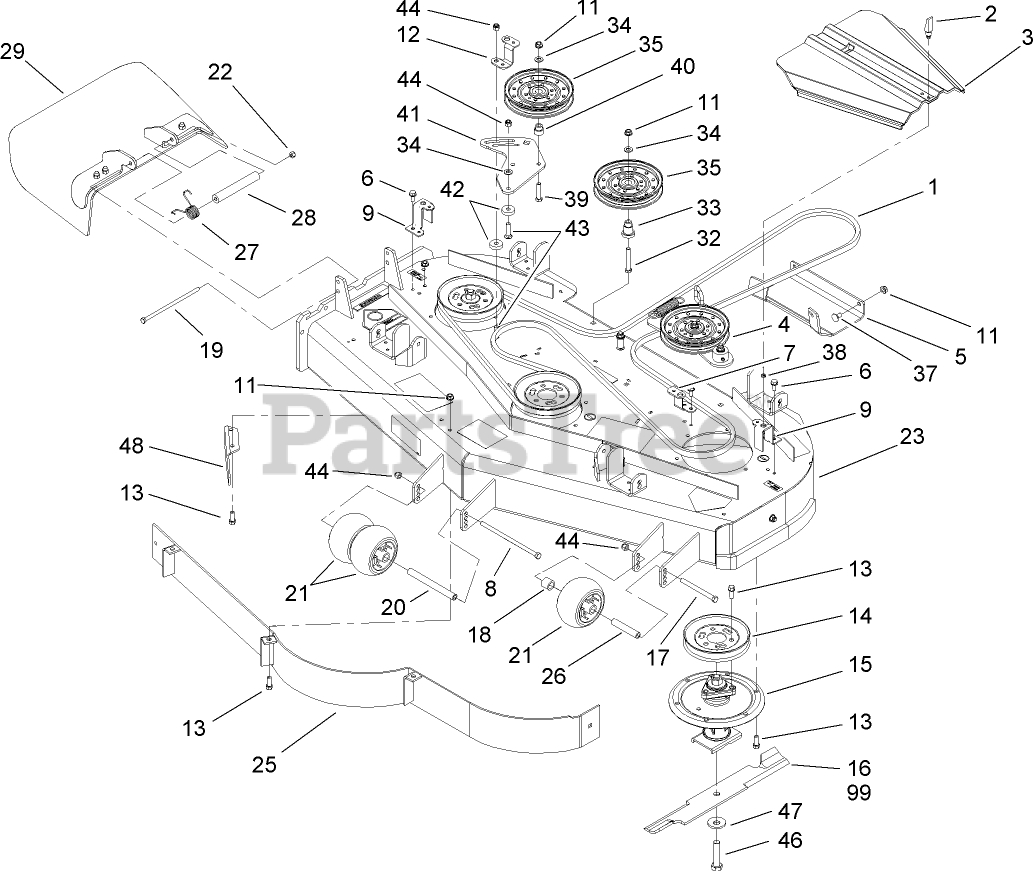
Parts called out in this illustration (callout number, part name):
1	BELT-V
2	LATCH-SWELL
3	COVER-BELT
4	SPRING IDLER ASM
5	Plate-Skid
6	SCREW-HWHTF
7	BRACKET-COVER, TALL
8	SCREW-HH
9	BRACKET-COVER
11	NUT-HHF, WHIZ
12	BRACKET-COVER, SHORT
13	SCREW-HWH
14	PULLEY
15	SPINDLE ASM
16	BLADE-18IN, HI FLOW
17	SCREW-HH
18	TUBE-SPACER
19	SCREW-HH
20	SPACER-WHEEL
21	ROLLER-SCALP, ANTI
22	NUT-LOCK, NI
23	DECK ASM
25	BAFFLE ASM
26	TUBE-SPANNER
27	SPRING-TORSION
28	SPACER
29	RUBBER DEFLECTOR ASM
32	SCREW-HH
33	MOUNT-PULLEY
34	WASHER-FLAT
35	Idler-Flat
37	SCREW-CARR
38	WASHER
39	SCREW-HH
40	BUSHING-IDLER
41	PLATE-IDLER
42	Spacer
43	SCREW-CARR
44	NUT-LOCK, NI
46	Screw-Cap
47	Washer-Blade Bolt, Heavy
48	BAFFLE-DISCHARGE
99	BLADE-MED FLOW
99	BLADE-RECYCLER
99	BLADE-LOW FLOW
99	BLADE-ATOMIC
